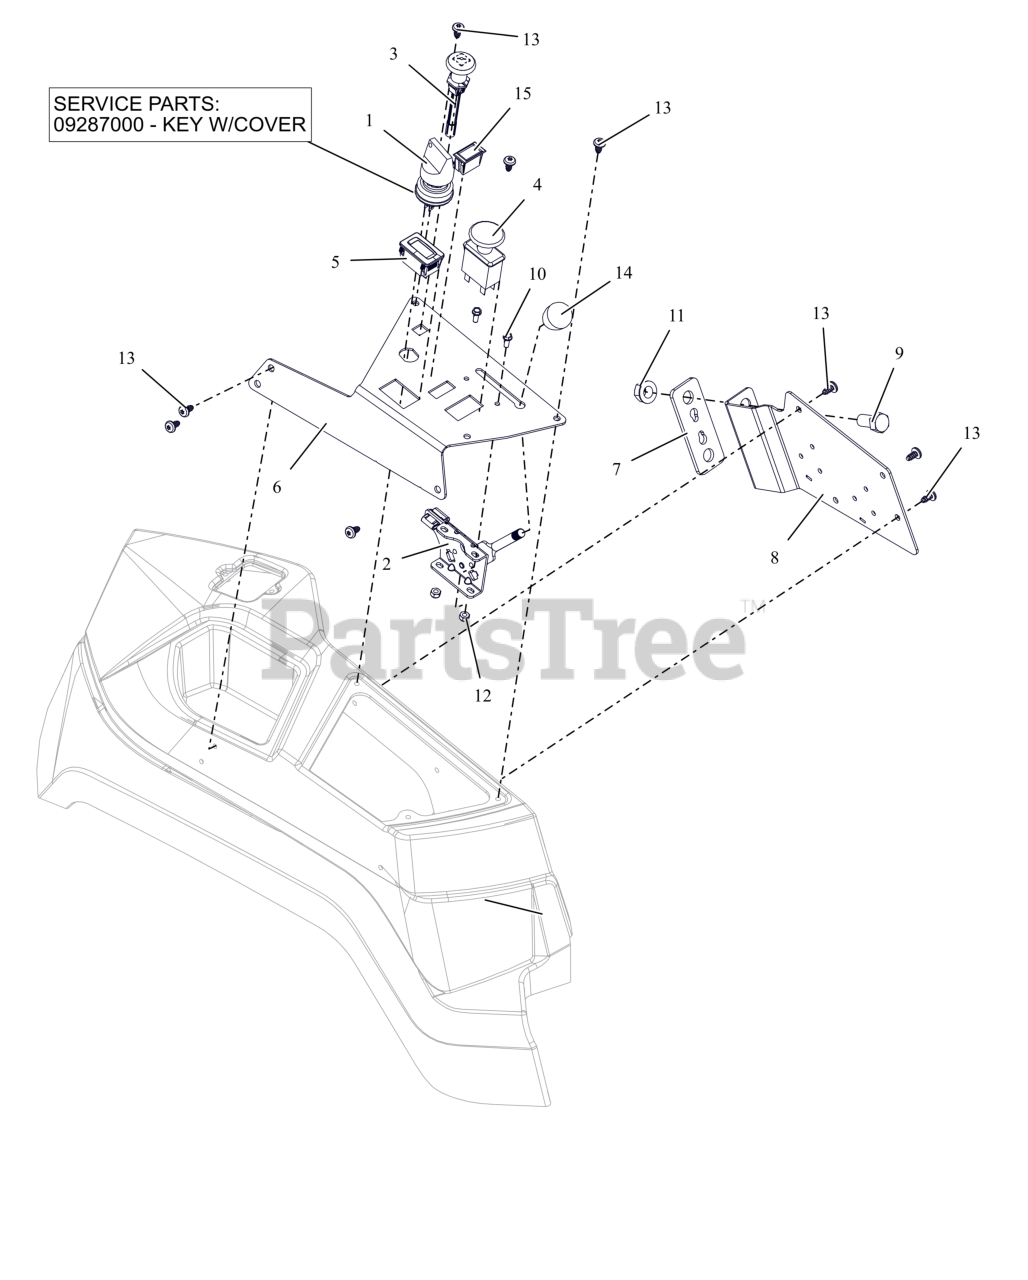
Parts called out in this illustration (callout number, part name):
1	SWITCH, IGNITION
1	KEY, W/ SHIELD
2	CABLE, PRO THROTTLE CONTROL
3	CABLE - CHOKE, SNAP-IN
4	SWITCH, CLUTCH
5	HOUR METER
6	PLATE, APEX CONTROL PANEL
7	PLATE, CONTROL PANEL SPACER
8	BRKT, FENDER/RELAY MOUNTING
9	BLT, HEX .50-13X1.00 G5 ZCC
10	BLT, HWH #10-24X.50 ZCC
11	NUT-LK-TOP-FLG .500-13 GF ZCC
12	NUT-LK-NYL #10-24 G2 ZCC
13	SCR-PAN .25-15X.50 6L H/LZB500
14	KNOB-CONTROL-BLACK .38-16X.50
15	SWITCH,BLANK
